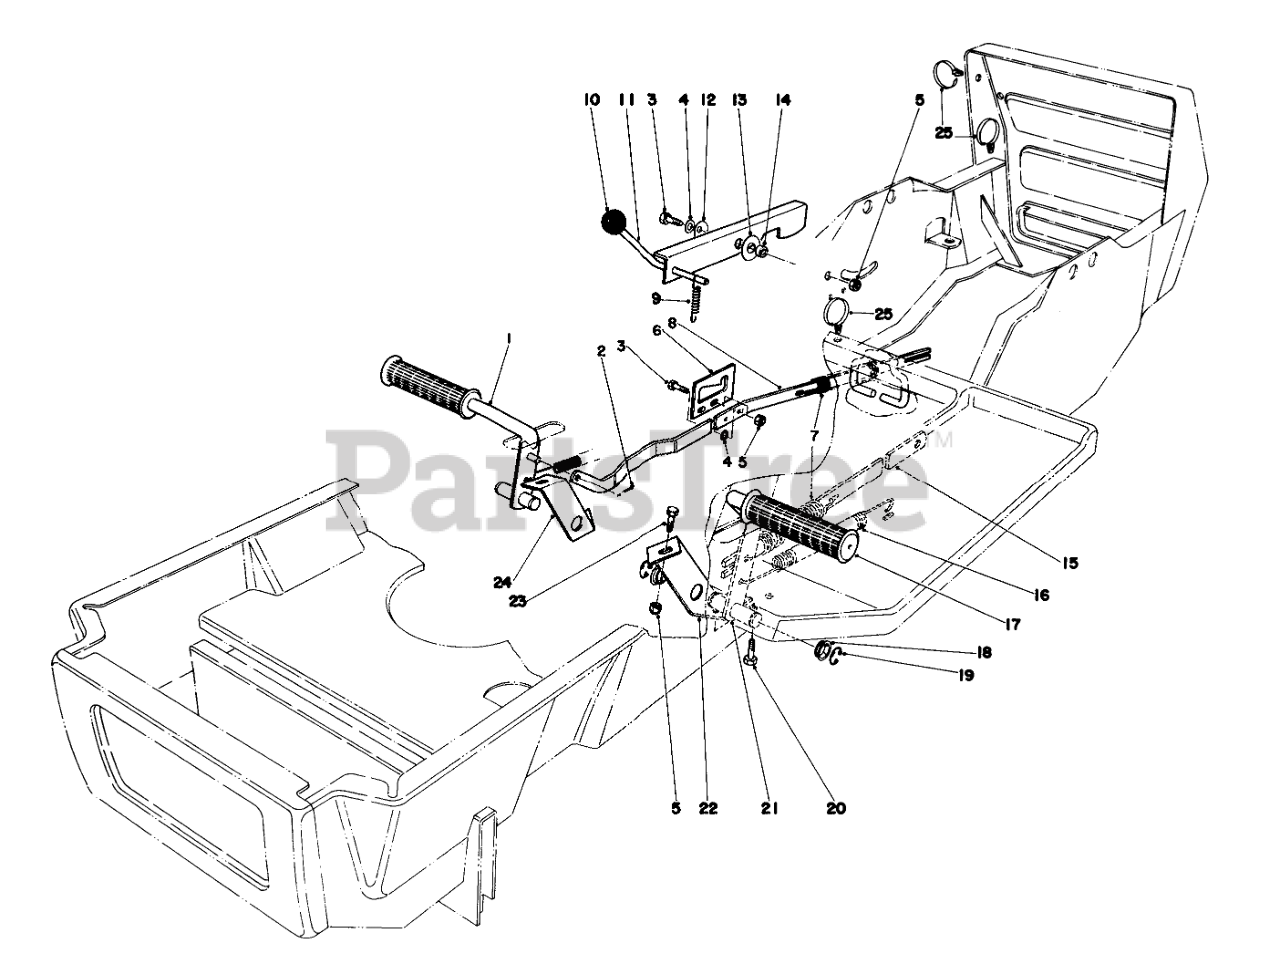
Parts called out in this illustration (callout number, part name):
1	BRAKE PEDAL WA BO
2	PIN-COTTER
3	SCREW-HH
4	WASHER-PLAIN
5	NUT-LOCK, CONE
6	LATCH PLT-BRAKE ROD
7	EXT SPRING O
8	LINK BRAKE ROD WAB
9	CONT ROD SPRING 0
11	PARKING BRAKE WA B
12	WASHER-BELLEVILLE
13	WASHER-PLASTIC
14	SPACER
15	CLUTCH ROD LINK B
16	SPRING-EXTENSION
17	Pad-Foot
18	Nyliner
19	E-RING
20	SCREW-HWHTF
21	CLUTCH PEDAL WA BO
22	LH PEDAL SUPT B
23	SCREW-HH
24	RH PEDAL SUPT B
25	TIE-MOUNT, PUSH
